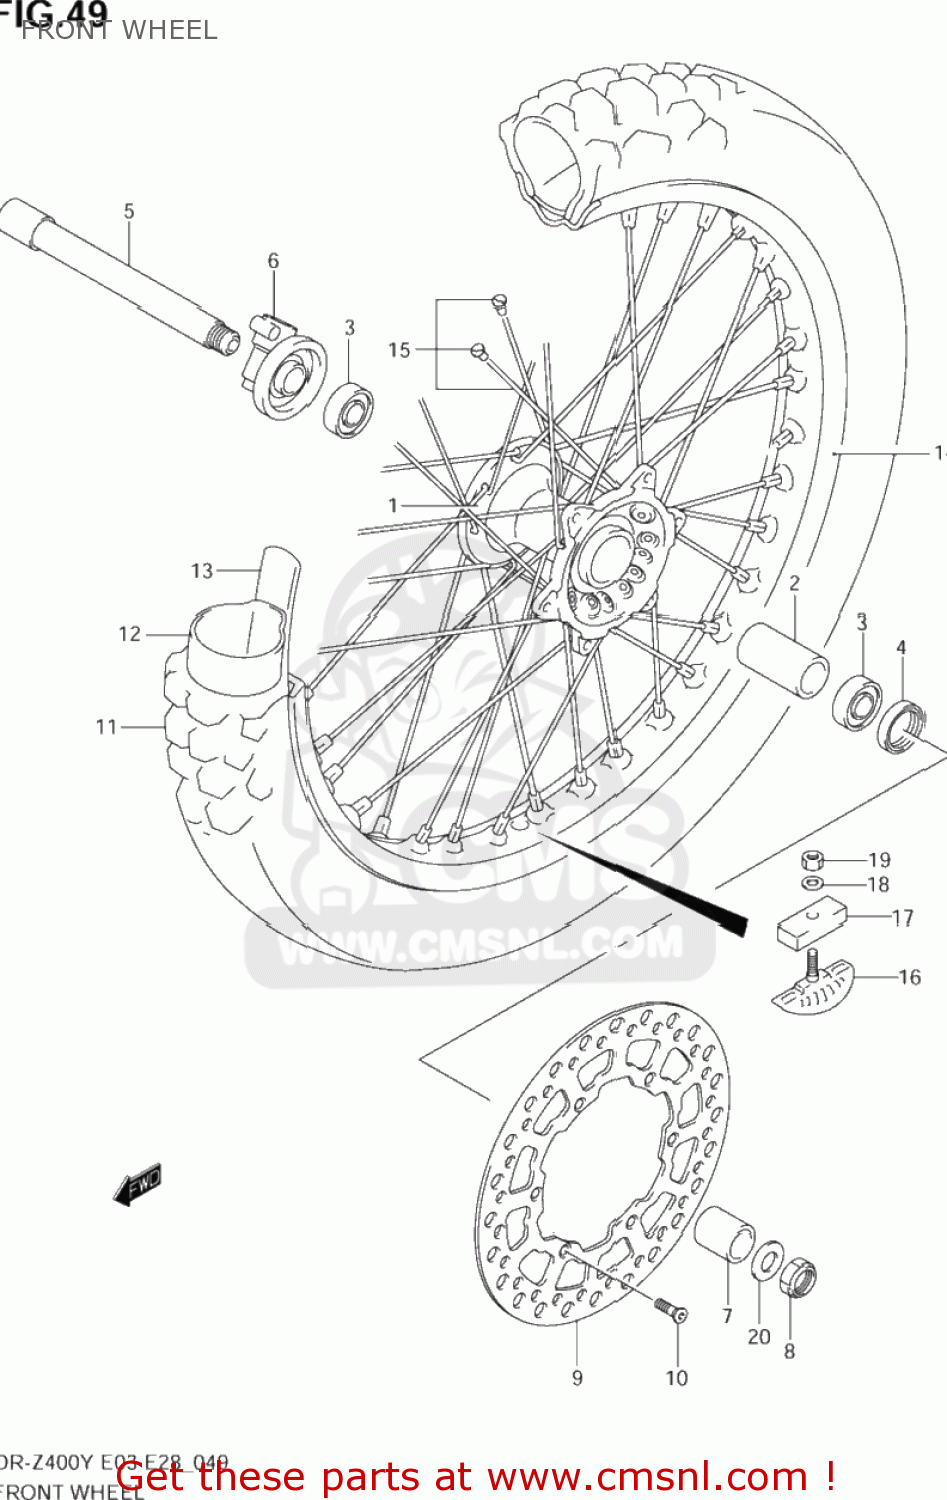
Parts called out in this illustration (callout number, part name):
1	HUB,FR WHEEL
2	SPACER,FR HUB BEARING
3	BEARING
4	SEAL,OIL(25X37X6)
5	AXLE,FR
6	BOX ASSY,SPEEDOMETER GEAR
7	SPACER,FR AXLE,L
8	NUT
9	DISC,FR BRAKE,L
10	SCREW
11	TIRE,FR(80/100-21 51M)
12	TUBE ASSY,WHEEL INNER
13	PROTECTOR,WHL INR TUBE
14	RIM,FR WHEEL(1.60X21 AL)(.WHT)
15	SPOKE SET,FR WHEEL
16	STOPPER,BEAD
17	CUSHION,BEAD STOPPER
18	WASHER
19	NUT
20	WASHER(18X26X2.8)
